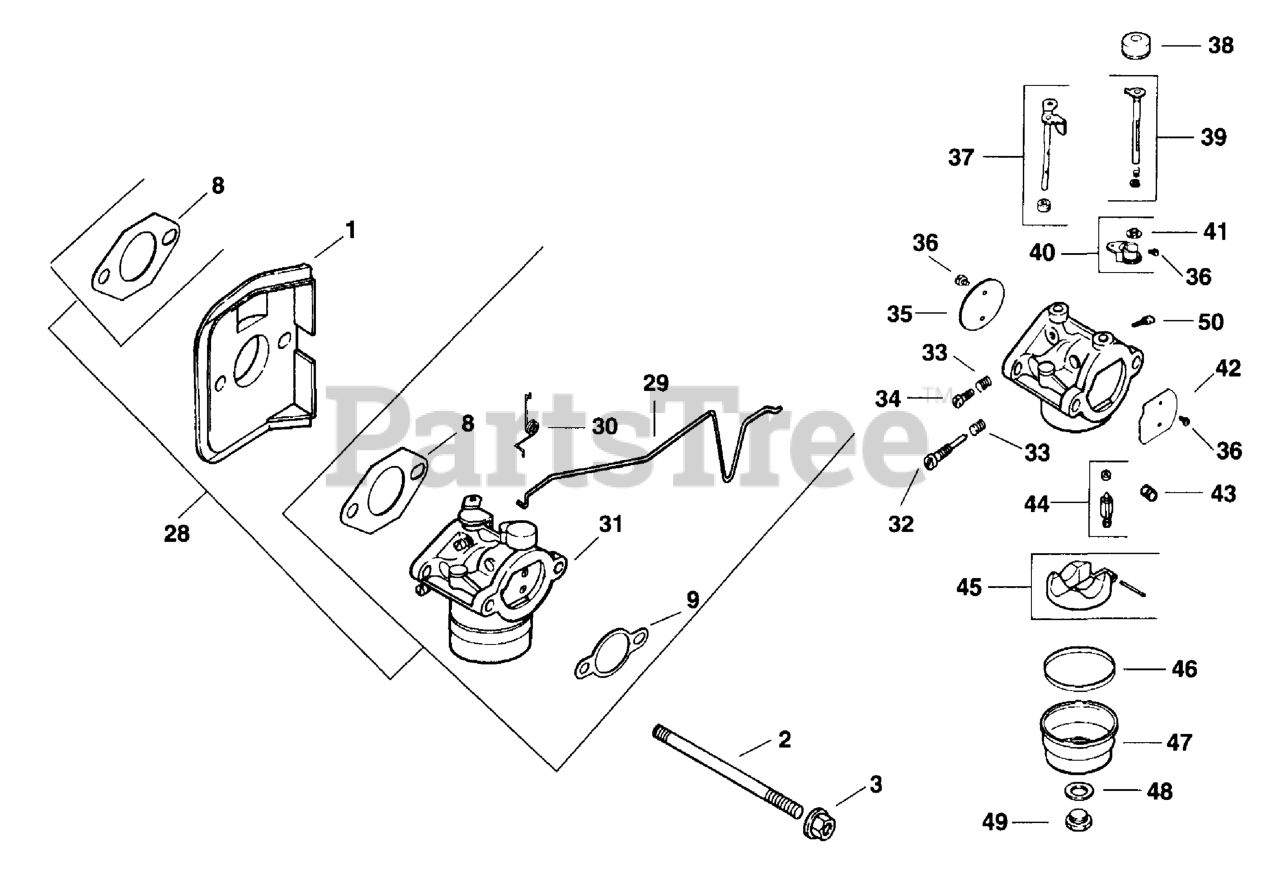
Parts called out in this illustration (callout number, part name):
1	DEFLECTOR - USE 12 265 04
2	Stud, carburetor M6x1.0x122.8
3	Nut, hex. flange M6x1.0
8	GASKET, CARBURETOR
9	GASKET, AIR CLEANER BASE
28	CARBURETOR - USE 12 853 49
29	LINKAGE, CHOKE
31	Carburetor assembly
32	NEEDLE, IDLE - DISCONTINUED
36	SCREW, VALVE
37	SHAFT, THROTTLE
38	CAP, CHOKE LEVER
39	SHAFT, CHOKE
40	KIT, CHOKE LEVER REPAIR - USE 12 757 32-S
41	BUSHING, CHOKE
42	PLATE, CHOKE
43	JET, MAIN - DISCONTINUED
44	Needle and Seat
45	KIT, REPAIR FLOAT
46	GASKET, FUEL BOWL
49	SCREW, FUEL BOWL RETAINER
